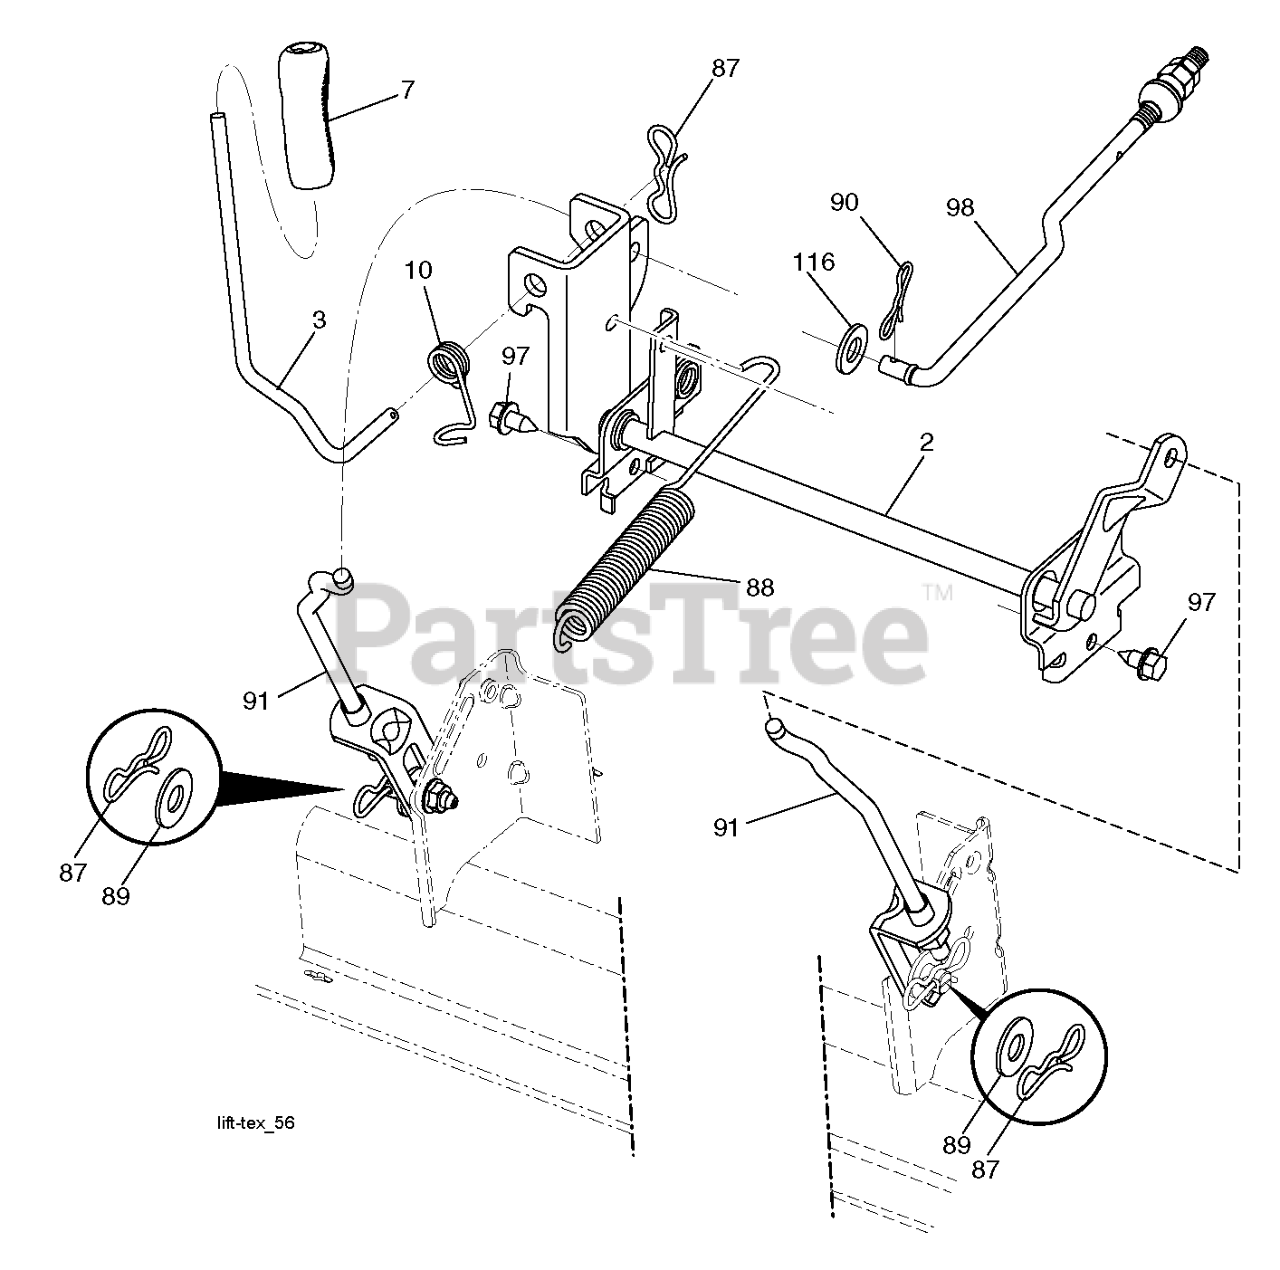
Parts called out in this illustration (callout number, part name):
2	SHAFT.ASM.CROSS.LIFT
3	LEVER.LIFT.HANDLE.LT
7	GRIP.HANDLE.LIFT.PVC.BLACK
10	SPRING.TORSION.LIFT.HANDLE
87	PIN.COTTER.7/16.BOW TI.
88	SPRING.LIFT.ASSIST
89	WASHER.CLEAR.ZINC
90	PIN.COTTER.5/16.BOW TI
91	LINK LINK;LIFT;REAR;ASM 46 X-F
97	SCREW, 3/8-16X3/4
98	LINK TABULATION;LINK;FRONT;MOW
116	Washer 15/32 x 15/16 x 16 Gauge (AYP part number)
